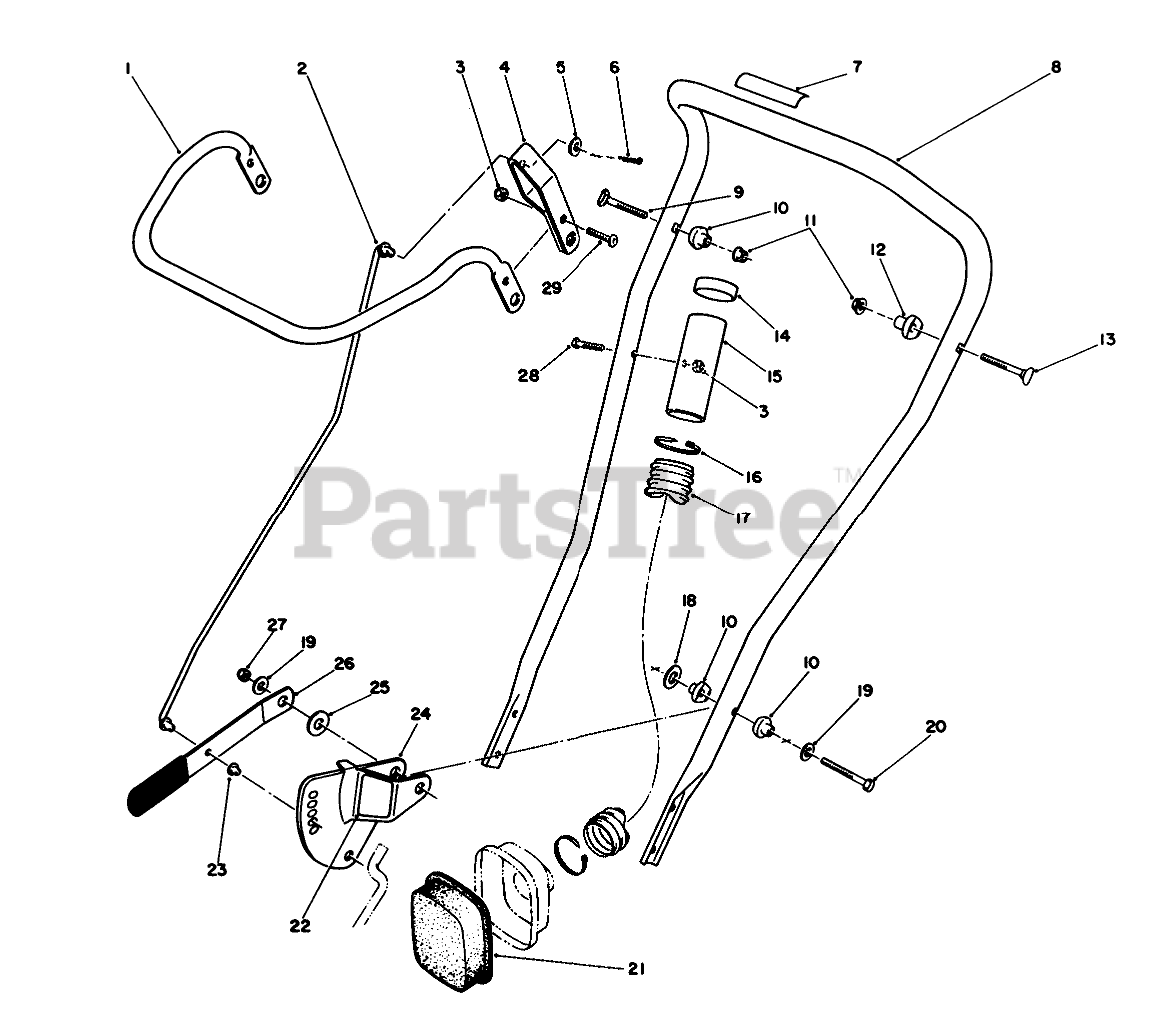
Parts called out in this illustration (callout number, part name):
1	30 Bar-Control
2	UPPER CONTROL ROD
3	NUT-LOCK, NI
4	CONTROL BAR BRKT.
5	WASHER-FLAT
6	PIN-COTTER
7	DECAL
8	UPPER HANDLE
9	SCREW-HANDLE
10	PIVOT SPACER
11	NUT-LOCK, NI
12	SPACER-SUPPORT
13	5/16-18 X 2 HNDLE SCREW
14	BLACK CAPLUG
15	AIR CLNR HOSE TIP
16	TIE-CABLE
17	AIR CLEANER HOSE
18	WASHER
19	WASHER-PLAIN
20	SCREW-HH
21	AIR CLEANER FILTER
22	DECAL
23	PUSHNUT
24	ADJ.PLATE WA
25	WASHER
26	ADJ.HANDLE
27	NUT-LOCK, NI
28	SCREW-HH
29	SCREW-HSBH
